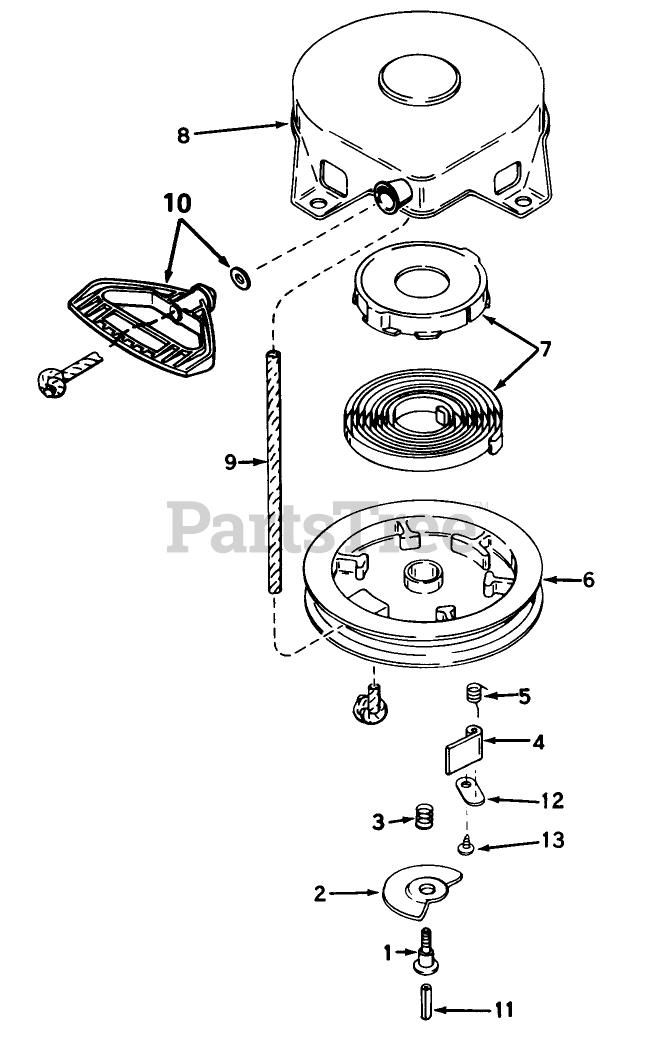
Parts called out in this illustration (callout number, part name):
1	Screw
2	Cam-Dog
3	Spring-Brake
4	Dog-Starter
5	Spring-Dog
6	Pulley
7	Spring Keeper Assy
8	Housing Assy.-Starter (Incl. Ref. #1)
9	Rope-Starter
10	Handle-Starter, Mitten Grip
11	Centering
12	Retainer-Dog
13	Screw
